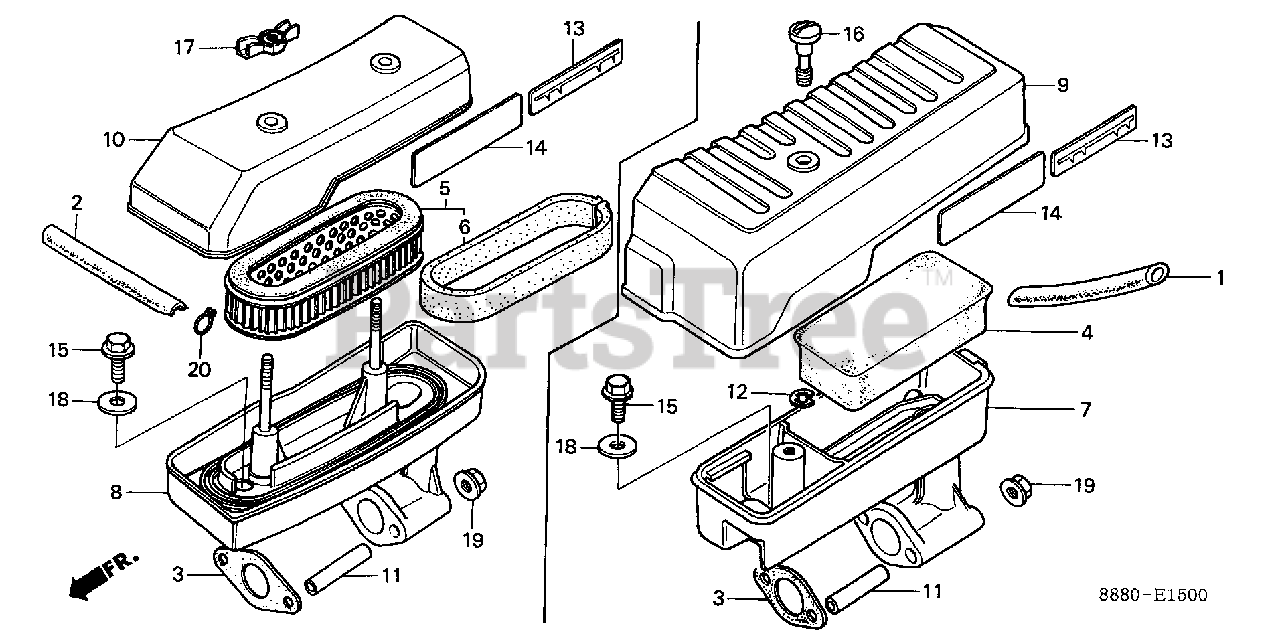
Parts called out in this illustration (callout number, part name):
2	TUBE, BREATHER (NOT AVAILABLE)
3	GASKET, AIR CLEANER
5	ELEMENT, AIR CLEANER
6	FILTER (OUTER)
8	HOUSING, AIR CLEANER
10	COVER, AIR CLEANER
11	COLLAR, AIR CLEANER HOUSING (NOT AVAILABLE)
13	MARK, CONTROL
14	MARK, AIR CLEANER CAUTION
14	MARK, AIR CLEANER CAUTION (NOT AVAILABLE)
15	BOLT, FLANGE (6X12) (CT200)
17	NUT, AIR CLEANER COVER (DACRO COATING)
18	WASHER, HEADLIGHT CASE
19	NUT, FLANGE (6MM)
20	CLIP, TUBE (B12.5)
